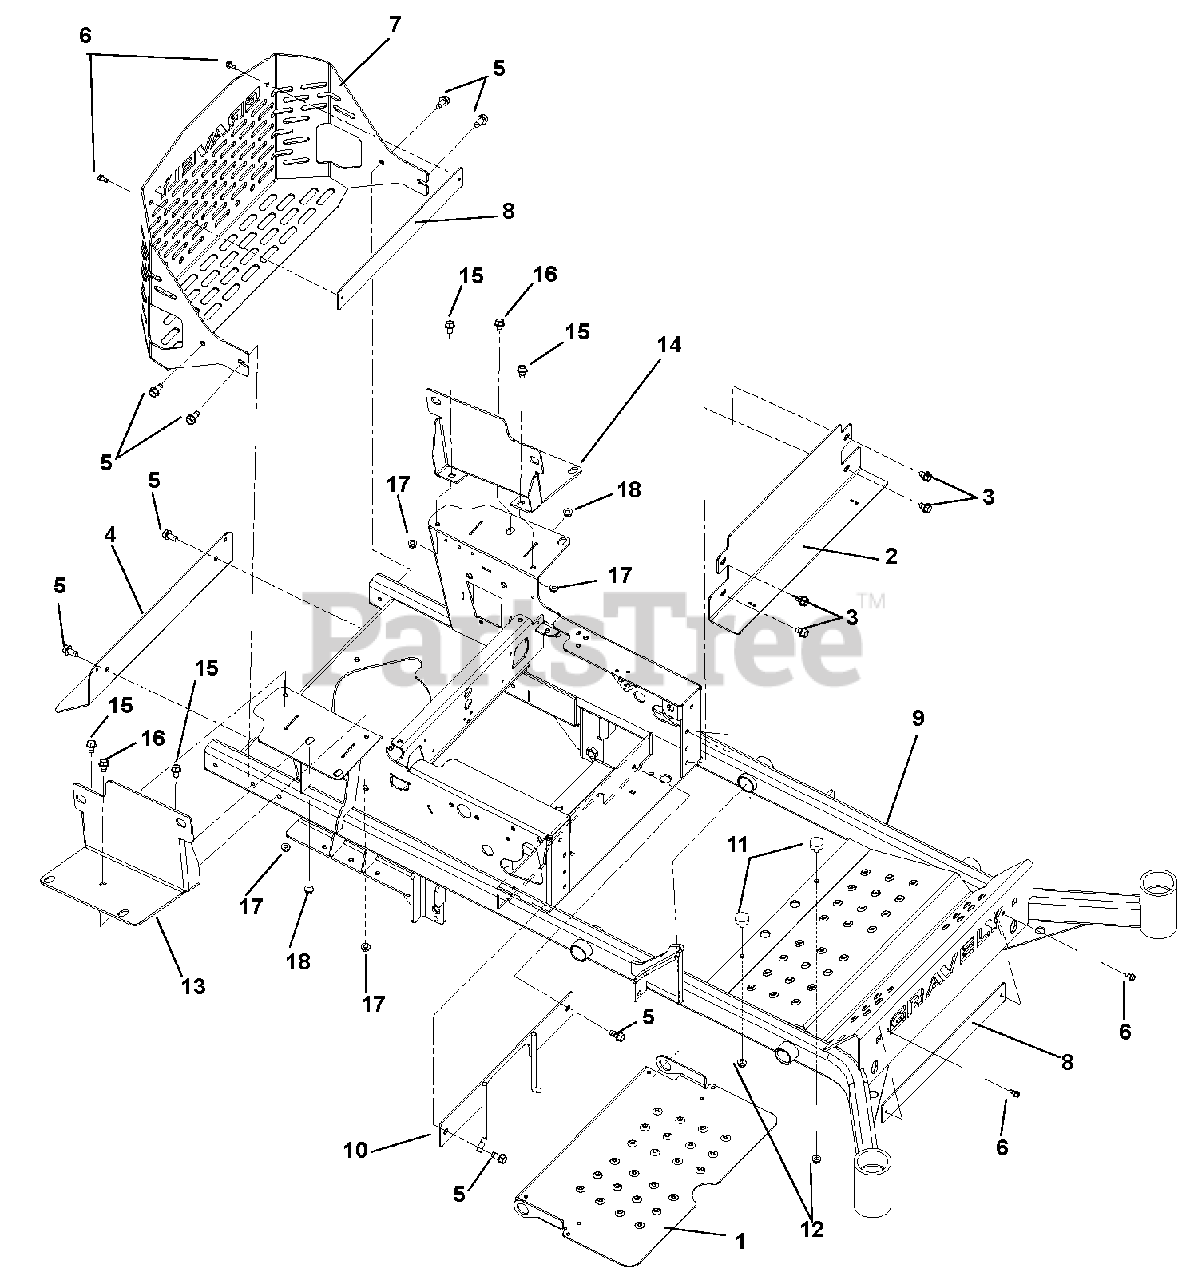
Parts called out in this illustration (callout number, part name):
1	Foot Plate
2	Kick Plate
3	Screw, Tapping .38-16 x .50 Hex Washer Head Thread Rolling
4	Muffler Heat Shield
5	Screw, Tapping .38-16 x .75 Hex Washer Head
6	Screw, Tapping .25-20 x .50 Hex Washer Head
7	Pro-Turn 100 Bumper
8	Bumper Plate
9	Pro-Turn 100 60" Main Frame Weldment (991081, 097, 104)
10	PTO Belt Finger Weldment
11	Bumper, Rubber
12	Nut, Spin Lock Flange .312-18
13	Bracket, Tank Mount Left Hand
14	Bracket, Tank Mount Right Hand
15	Bolt, Round Head Square Neck .38-16 x 1.00 Grade 5
16	Bolt, Round Head Square Neck .31-18 x .75 Grade 5
17	Nut, Nyloc Flange .38-16
18	Nut, Nyloc Flange .31-18
